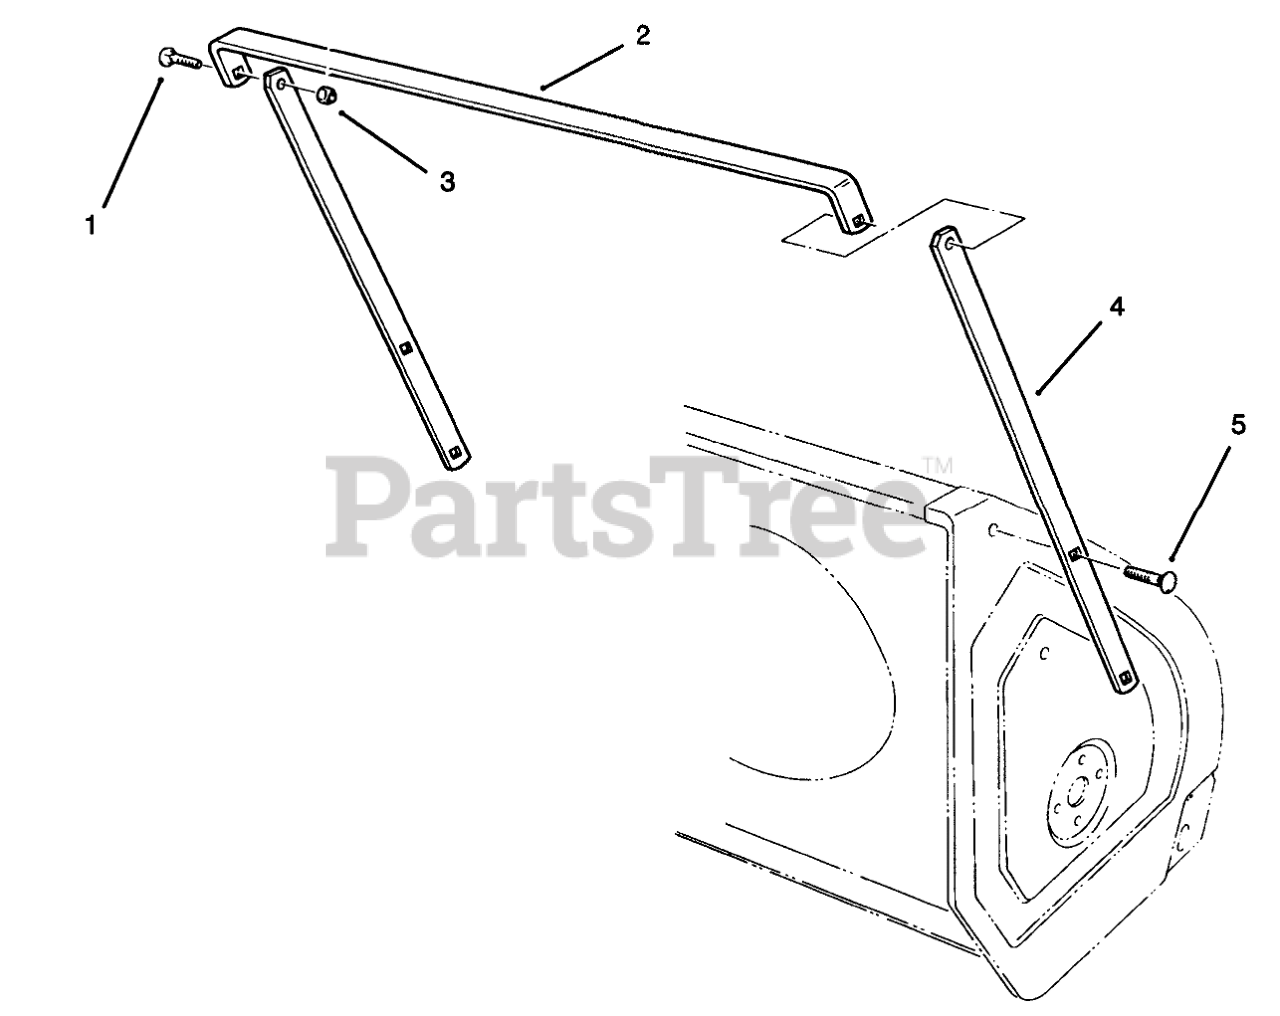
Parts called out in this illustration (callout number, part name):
1	SCREW-CARR
3	NUT-LOCK, NI
4	Breaker-Side
5	BOLT-CARR
